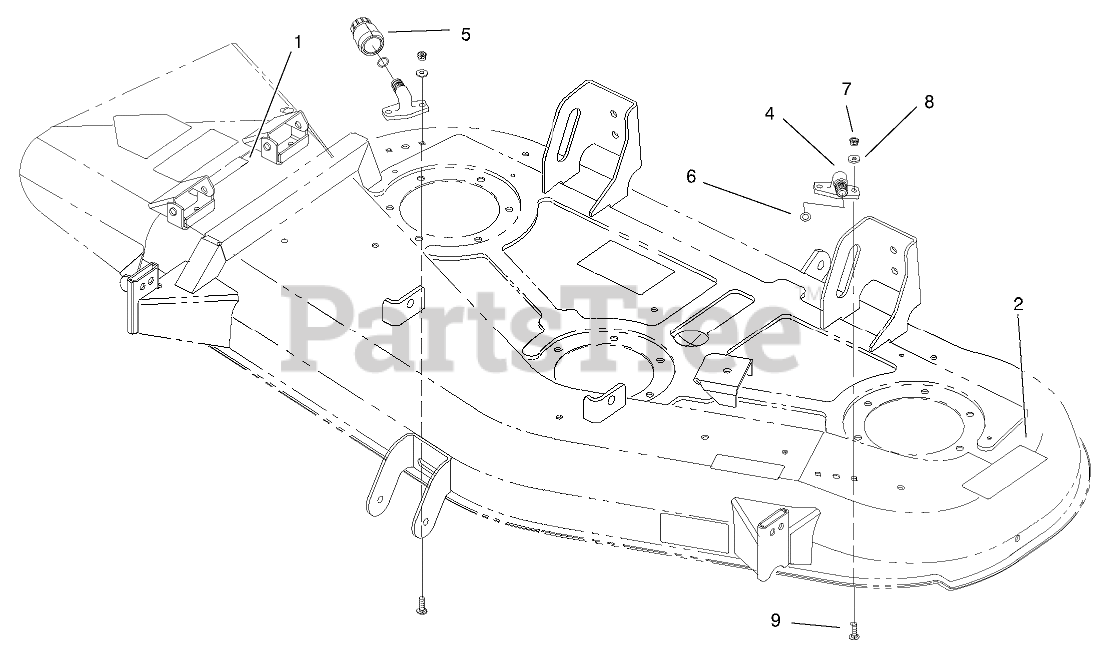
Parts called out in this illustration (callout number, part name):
1	DECAL-CAUTION
2	DECAL-DANGER
4	FITTING-WASHOUT
5	CONNECTOR-HOSE
6	O-RING
7	NUT-LOCK, NI
8	WASHER-FLAT
9	BOLT-CARR
